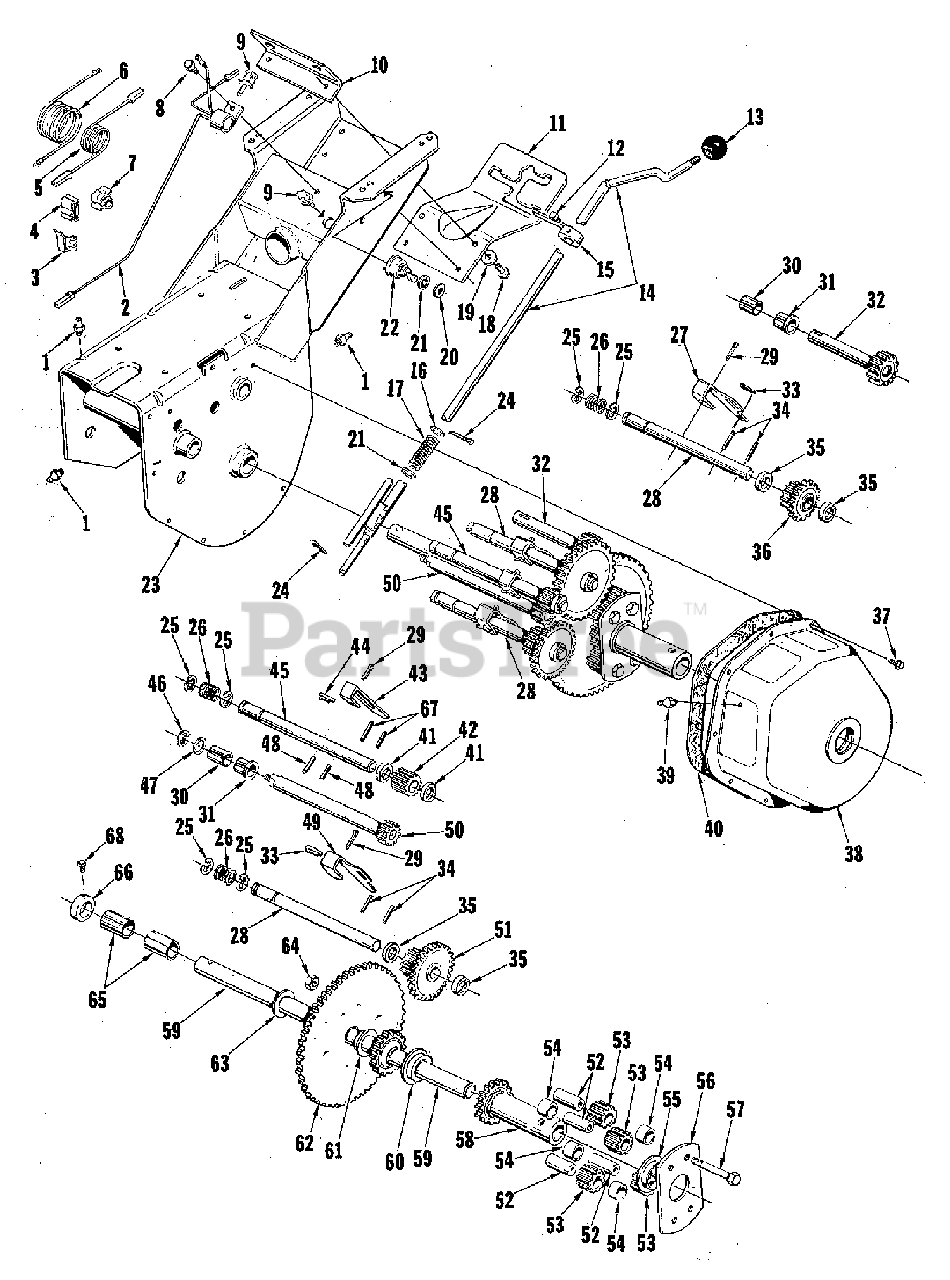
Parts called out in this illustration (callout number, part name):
1	FITTING, Grease
2	IGNITION, Interlock
3	CLIP, Speed Cable
4	CLIP, Speed Cable
8	SCREW, Hex, 1/4-20 x 3/8
9	SWITCH, Interlock
10	GUIDE, Shift Rod
11	PLATE, Shift Pattern
12	SCREW, Set, 5/16-18 x 3/8
15	LEVER, Shift Rod
16	SPACER, Washer
18	SCREW, Hex, Taptite, 1/4-20 x 5/8
19	WASHER, Flat, 1/4
20	NUT, Hex, 8-32
21	WASHER, Lock, (Intermediate) #8
22	SWITCH & KEY
23	BASE FRAME & SEAT SUPPORT
24	PIN, Cotter, 1/8 x 1
26	SPRING, Compression
27	LINK, Shift, High
28	SHAFT, Intermediate
29	PIN, Cotter, 3/16 x 1-1/4
30	BEARING, Bronze
31	BEARING, Bronze
32	SHAFT & GEAR, Brake
33	PIN, Cotter, 3/32 x 3/4
34	PIN, Roll, 1/8 x 1
35	COLLAR, Thrust
36	GEAR & BEARING, High
37	SCREW, Taptite, 1/4-20 x 3/8
39	FITTING, Grease
40	GASKET, Gear Case
41	COLLAR, Thrust
42	PINION, Reverse
43	LINK, Shift, Reverse
44	PIN, Cotter, 1/16 x 3/4
45	SHAFT, Reverse
46	RING, Retaining
48	PIN, Roll, 5/32 x 1
49	LINK, Shift, Low
51	GEAR & BEARING, Low
52	SPINDLE, Pinion Differential
53	PINION, Differential
54	SPACER, Differential
55	BUSHING, Differential
56	PLATE, Differential
57	SCREW, Hex, 3/8-16 x 2-1/2
58	AXLE & BUSHING, R.H.
61	BUSHING, Drive Gear
64	NUT, Hex Lock, 3/8-16
67	PIN, Roll, 1/8 x 2/4
68	SCREW, Set, 5/16-18 x 1/2
